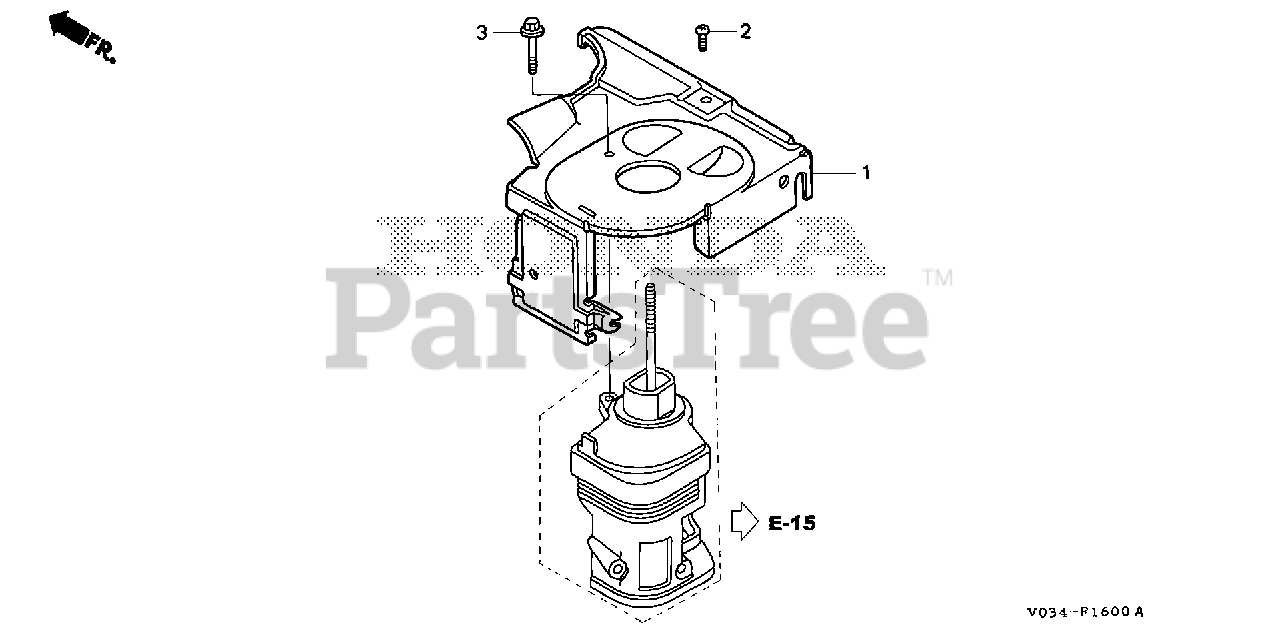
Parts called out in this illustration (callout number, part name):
1	COVER, CONTROL (HS)
2	SCREW, PAN (6X8) (SOURCE: VINTAGE PARTS INC.)
3	BOLT, FLANGE (6X35)
